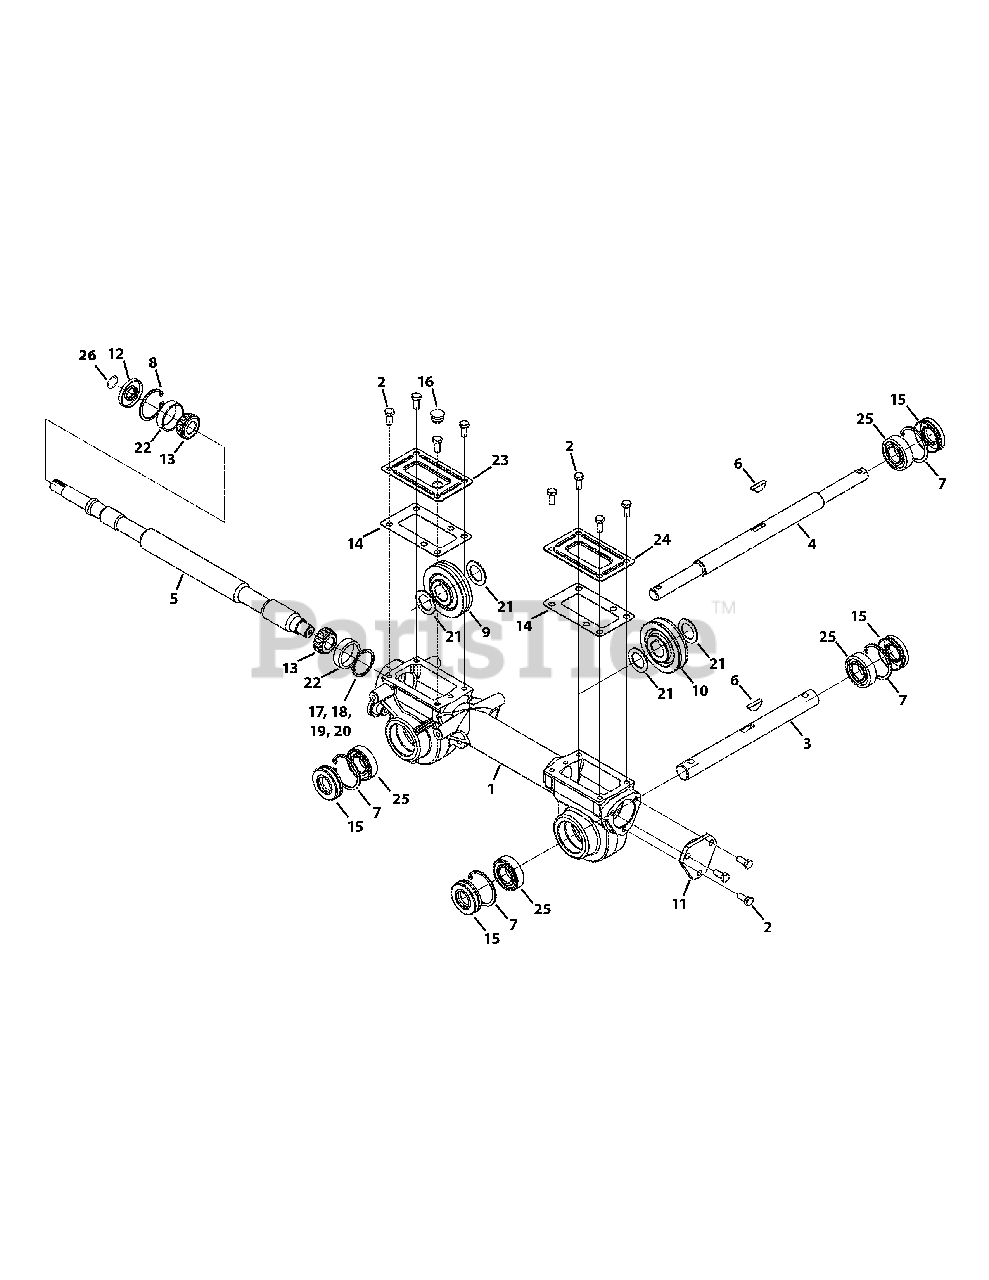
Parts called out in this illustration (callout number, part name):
1	Transmission Housing
2	Hex Head Screw, 5/16-18 x .75
3	Tiller Shaft
5	CRT Drive Shaft 02-23-09 & Before
5	CRT Drive Shaft 02-23-09 & After
6	Key, .25 x 1.062
7	Retainer Key
8	Retainer Ring
9	RH Gear Worm, 61T
10	LH Gear Worm, 30T
11	Bearing Cover
12	Oil Seal, .750 SHF x 1.783 BORE
13	Cone Bearing
14	Gear Housing Gasket
15	Oil Seal, 1.00 SHF x 2.00 BORE
16	Rubber Oil Plug
17	Washer, Flat, 1.50 x 1.75 x .062
18	Washer, Flat, 1.50 x 1.75 x .005
19	Washer, Flat, 1.50 x 1.75 x .03
20	Washer, Flat, 1.50 x 1.75 x .010
21	Washer, Flat, 1.010 x 1.56 x .060
22	Cup Bearing
23	Tiller Transmission Cover
24	Tiller Transmission Cover
25	Ball Bearing, 1 x 52 x 15 x 6205-1
26	Wire Ring 02-23-09 & After
